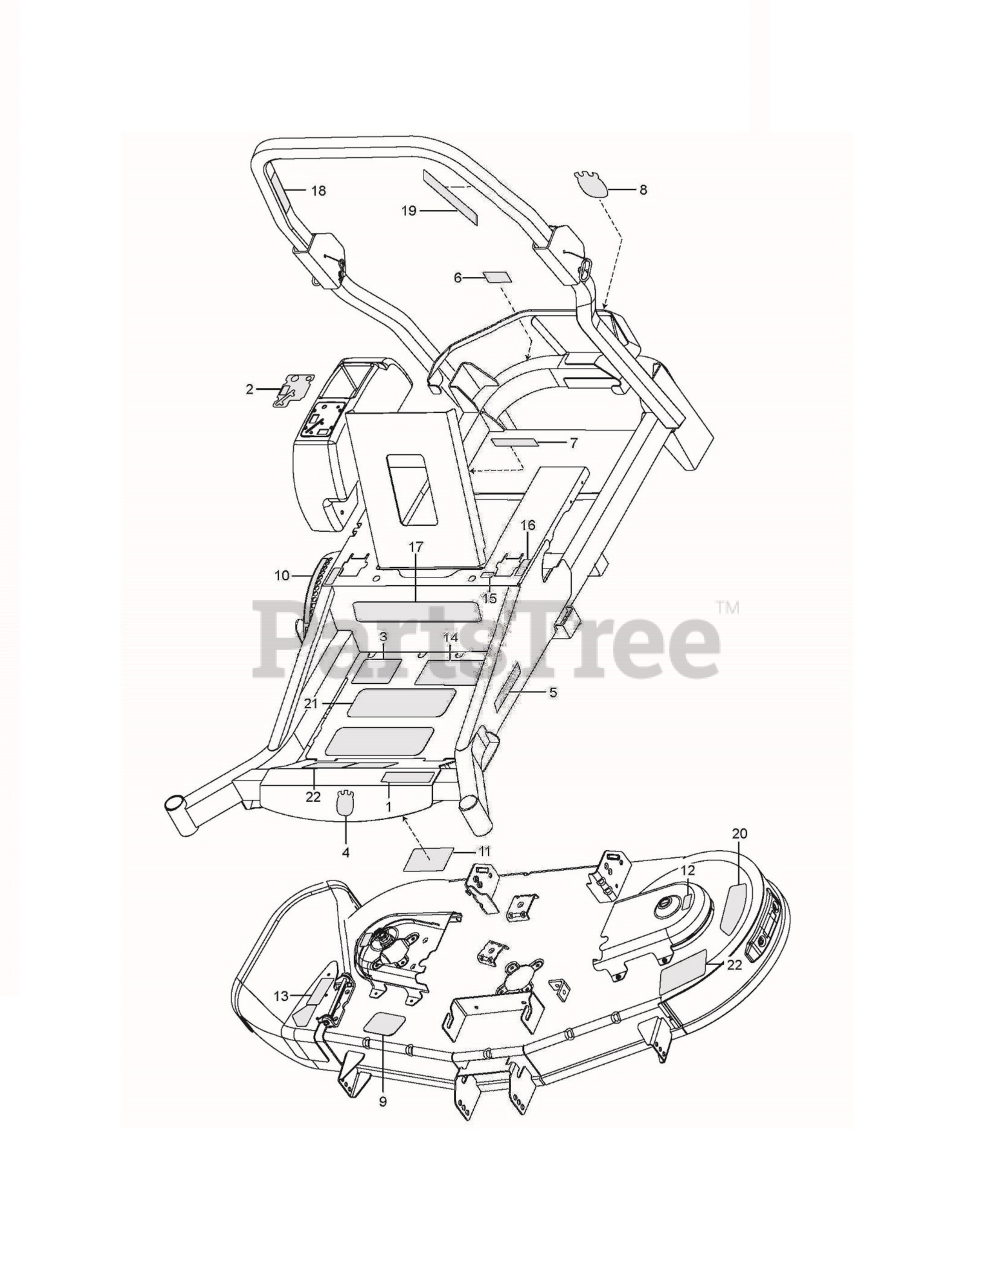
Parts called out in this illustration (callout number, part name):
1	DECAL ZTR MODEL NUMBER DECAL.Z
2	DECAL, CONSOLE HUS
3	DECAL.ZTR.STRTNGINST.REMOTECHK
4	DECAL.AUGER.HUSQ.CROWN.SNOW
5	RP.DECAL.BADGE.170MM.TEXTLOGO
6	DECAL, BELT DRIVE
7	EURO DECAL-BATTERY WARNIN6
8	DECAL, CROWN H, 110MM
9	DECAL BELT ROUTING DECAL DECAL
10	DECAL, HEIGHT ADJUST
11	DECAL, SERVICE
12	DECAL.DECK.CLEARCUT.NOSTEP
13	DECAL.TRACT/ZTR.DECKWARN.HUSQ
14	DECAL ZTR WARNING DECAL DECAL.
15	DECAL.STR.S.T.SYSMBOLONLY.2014
16	DECAL.ZTR.MOTCONTRL.SYMBOL.HUS
17	DECAL ZTR BRAND GRAPHIC DECAL.
18	DECAL, ROPS, WARNING
19	DECAL ROPS
20	DECAL.54DECK.CLEARCUT.VER2.18
21	ANTI-SKID PAD
